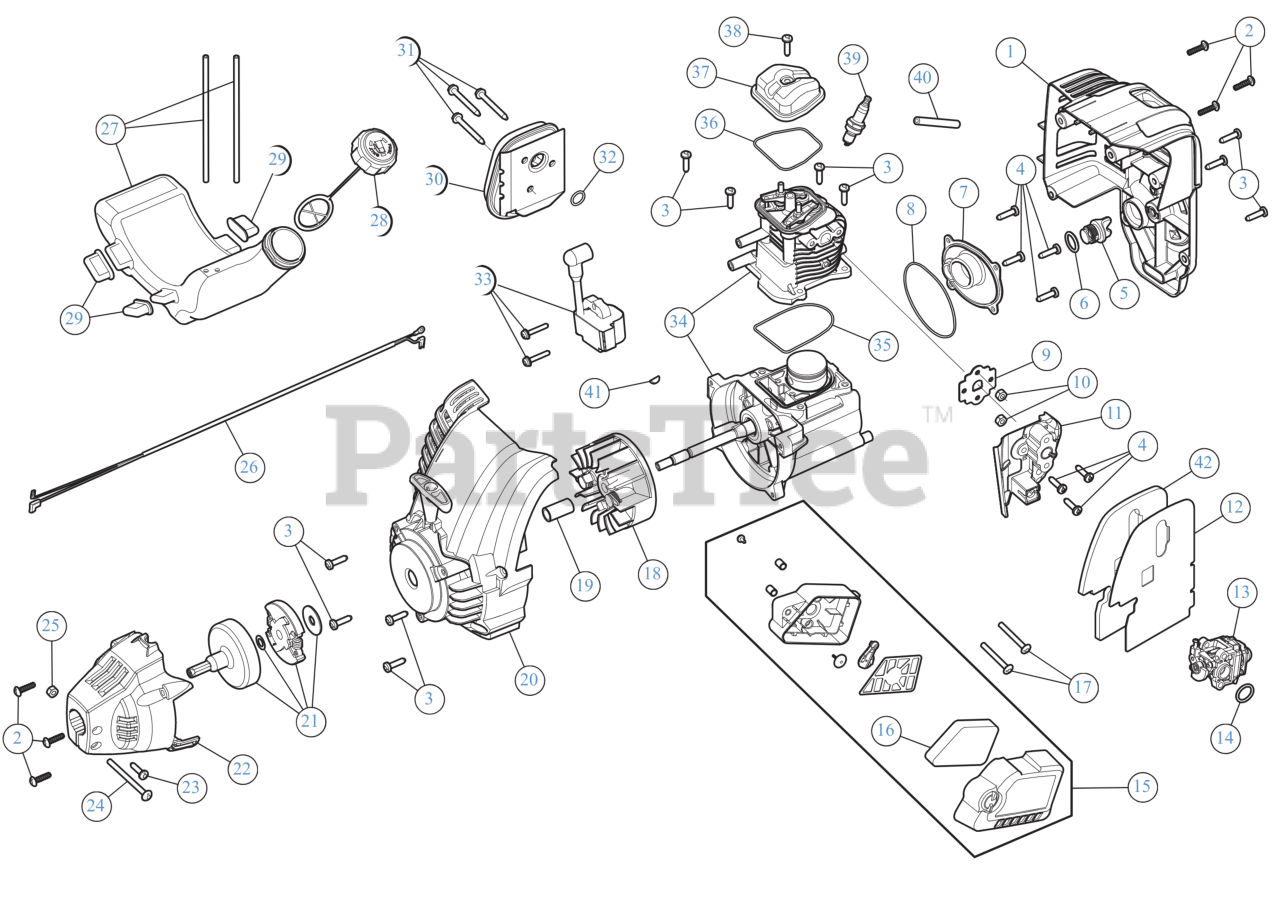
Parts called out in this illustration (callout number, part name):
1	ENGINE COVER ASSEMBLY RR
2	SCREW 8-16 x 3/4
3	SCREW M5-0.8 x 19
4	SCREW, M5 x 18.7MM
5	OIL PLUG
6	RING, OIL PLUG (AC
7	CRANKCASE COVER
8	O-RING CRNKCSE CVR
9	GASKET/INSULATOR
10	NUT 10-32
11	CARB INSULATOR
12	GASKET
13	CARBURETOR
15	AIR CLEANER
16	AIR FILTER
17	SCREW 10-32X2.5
18	FLYWHEEL ASSEMBLY AC3.1
19	SPACER :2.165"
20	STARTER HOUSING (LIB RED)
21	CLUTCH ASSEMBLY
22	CLUTCH COVER ASSEMBLY
23	SCREW 8-18X.375 T-20
24	SCREW
25	HEX NUT
26	WIRE LEAD
27	FUEL TANK ASSEMBLY
28	FUEL CAP ASSEMBLY 43MM-6 W/O HOLE
29	FUEL TANK PADS
30	MUFFLER ASSEMBLY
31	SCREW M5 x 44MM
32	GASKET/MUFFLER
33	MODULE ASM
34	SHORT BLOCK
35	O-RING CYL AC5
36	O-RING
37	ROCKER COVER
38	SCR, VALVE COVER
39	SPARK PLUG 4 CYCL
40	BREATHER HOSE
41	WOODRUFF KEY #403-.125 x .375
42	HEAT SHIELD
